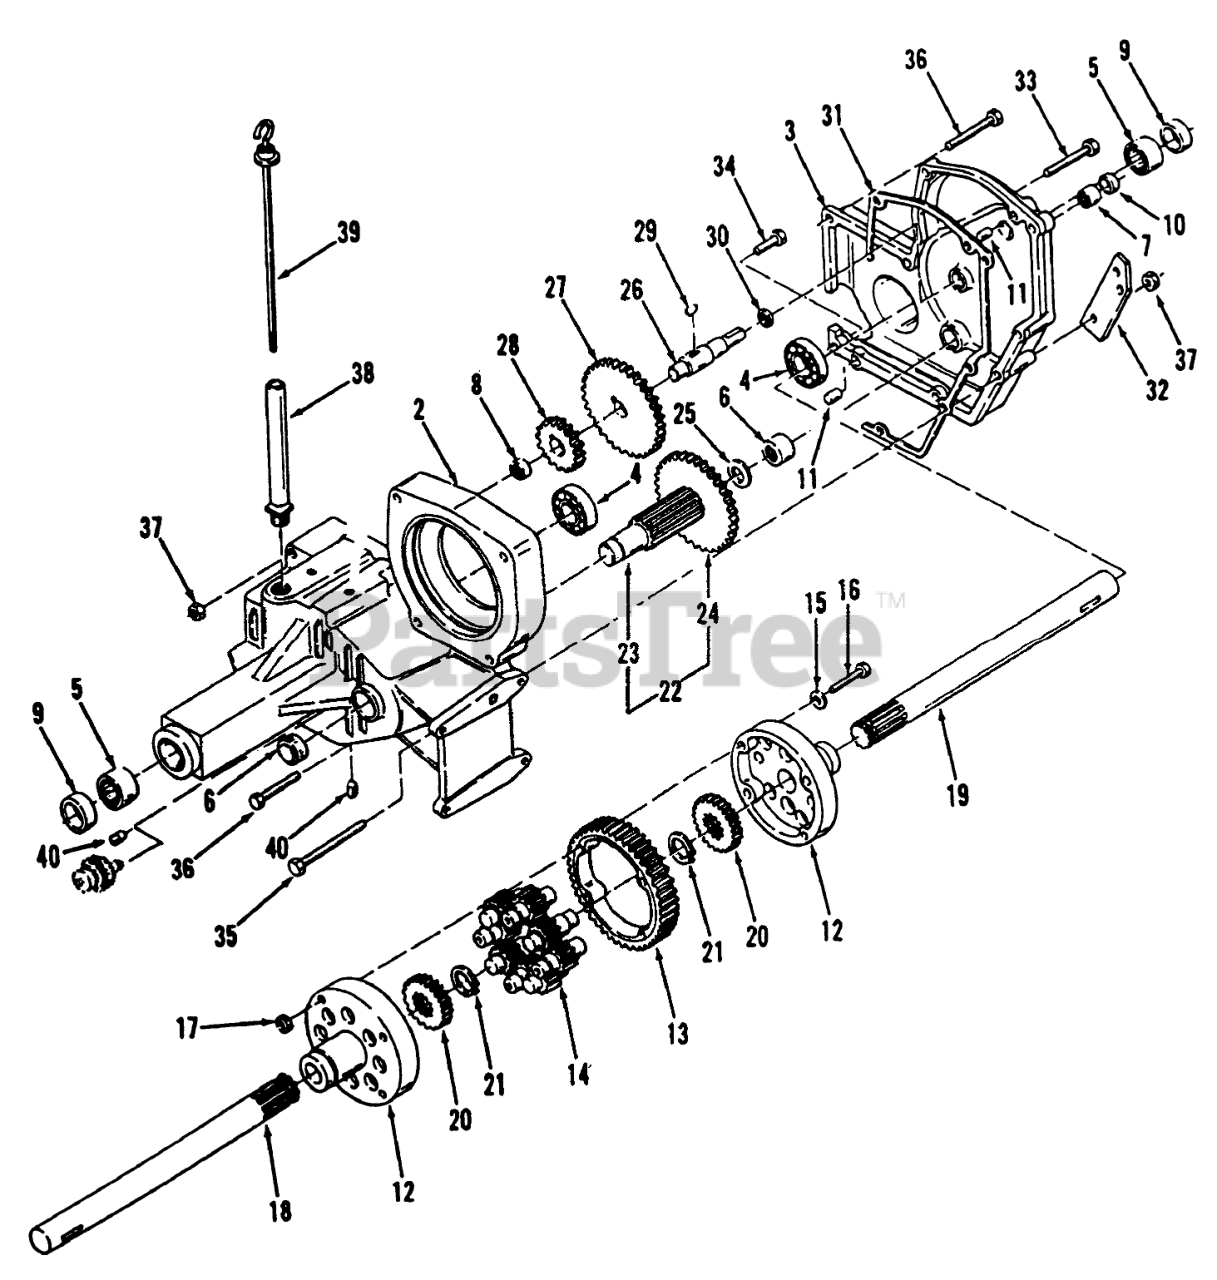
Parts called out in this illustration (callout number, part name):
1	Transaxle Complete
2	CASE-TRANS RH
3	CASE TRANS LH
4	BEARING-BALL
5	BEARING
6	BEARING-NEEDLE
7	NEEDLE BEARING
8	BEARING-NEEDLE
9	SEAL-OIL
10	Seal
11	PIN-LOCATING
12	END CAP-DIFFERENTIAL
13	GEAR-DIFFERENTIAL RING, 43T
14	GEAR-PINION, 11T
15	WASHER
16	BOLT-HEX
18	AXLE-REAR RH
19	AXLE-REAR LH
20	GEAR-AXLE DIFFERENTIAL
21	RING-SNAP
22	ASSY GEAR
23	PINION SHAFT
25	WASHER-THRUST
26	SHAFT GEAR
27	GEAR 46 TEETH
28	GEAR 20 TEETH
29	Key
30	Race Thrust
31	GASKET-TRANSMISSION
32	BRACKET-BRAKEB
33	Bolt
34	SCREW-HH
35	SCREW-HH
36	SCREW-HH
37	NUT-LOCK, NI
38	NIPPLE-TRANS FILL
39	Dipstick
